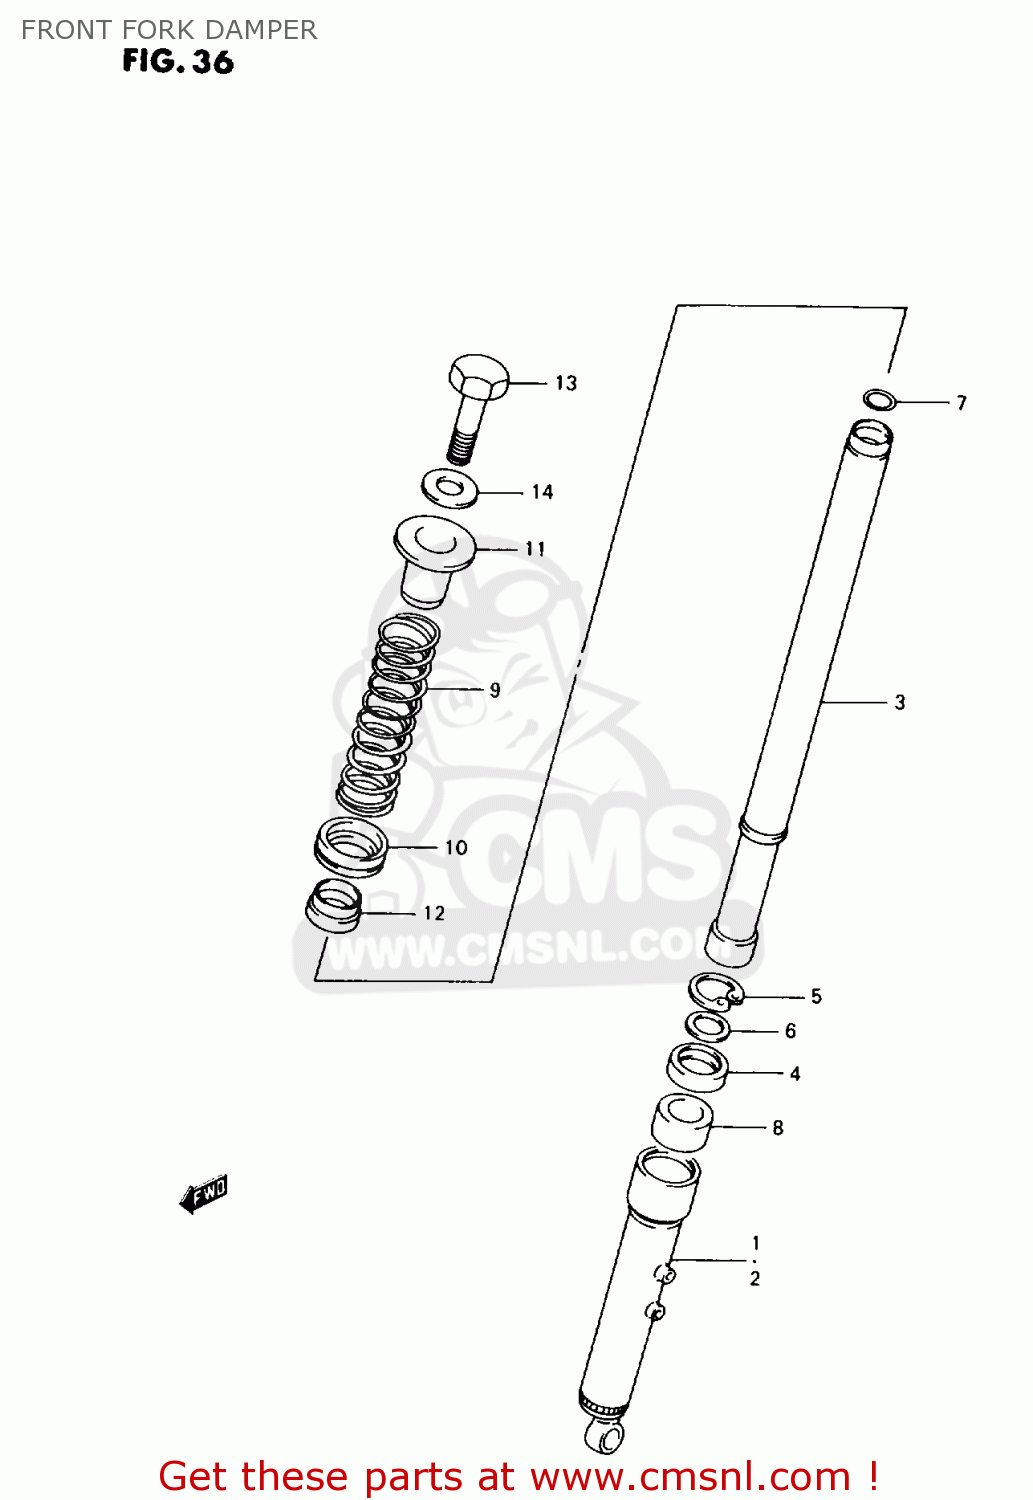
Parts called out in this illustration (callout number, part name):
1	TUBE,OUTER,R
2	TUBE,OUTER,L
3	TUBE,FORK INNER
4	SEAL,OIL
5	RING,SNAP
6	WASHER
7	O RING
8	METAL,SLIDE
9	SPRING,FR FORK
10	GUIDE,SPRING
11	GUIDE,SPRING
12	GUIDE,SPRING
13	BOLT,FR FORK(10X33)
14	WASHER,STEERING STEM HEAD
